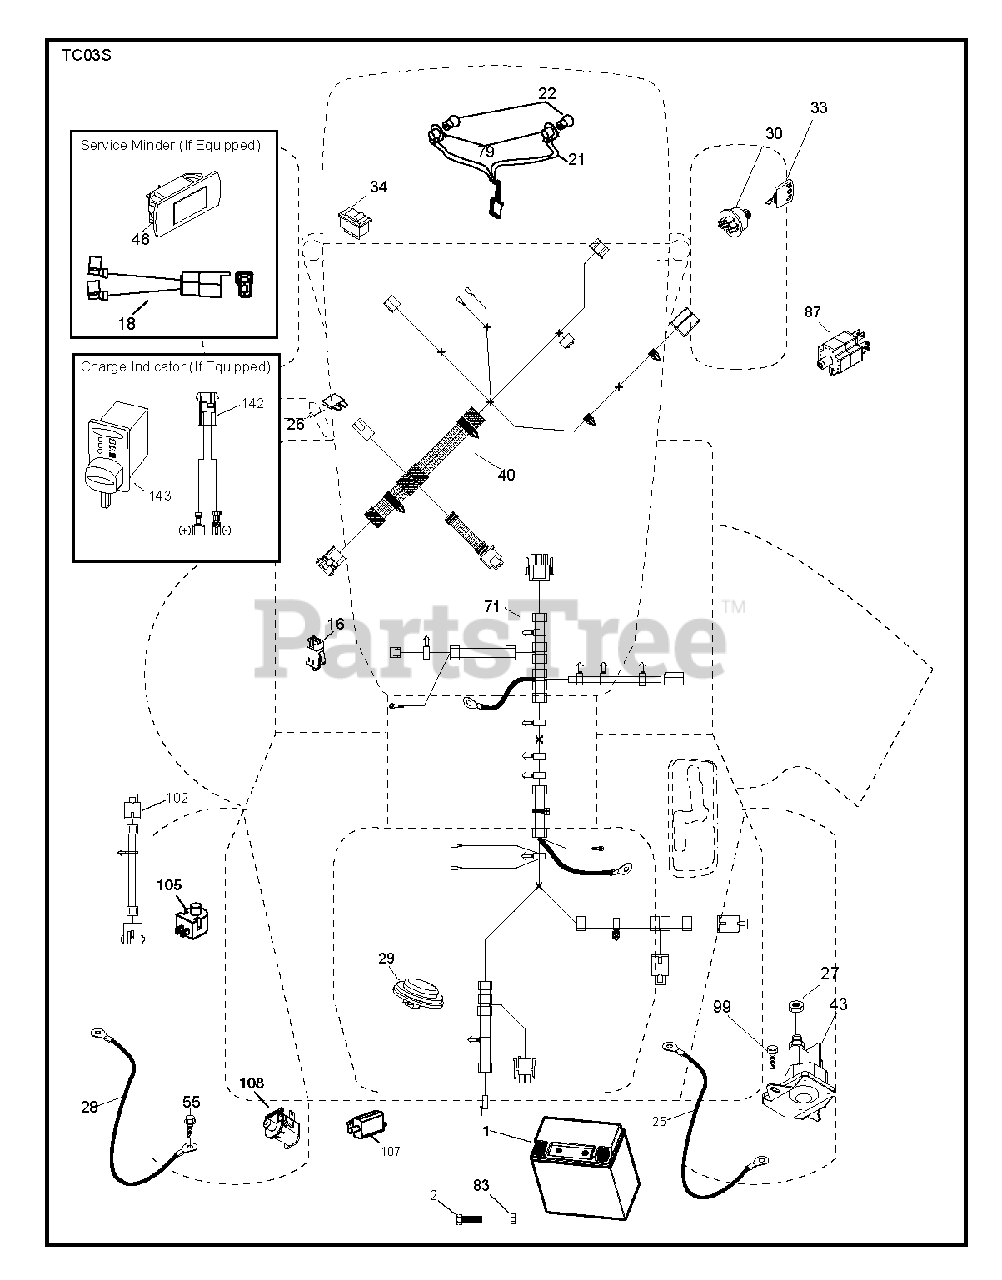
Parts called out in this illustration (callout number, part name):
16	SWITCH INTERLOOK PUSH-IN
21	HARNESS.LIGHT W/4152J BULBS
22	LIGHTBULB
26	FUSE 20AMP
27	NUT
29	SWITCH.SEAT.DELTA.OPC.
30	SWITCH.IGN.DELTA.W.LGH.ROS
33	KEY.CHAIN.BLISTER.PACK.GEN.INT
34	SWITCH LT
43	SOLENOID.W/BRASS.PLUNG
46	Hour Meter Gauge
55	SCREW 5/16"
79	BULB HOLDER ASM.
99	SCREW
105	REVERSE SWITCH
108	SWITCH.SNAPMOUNT.NC
